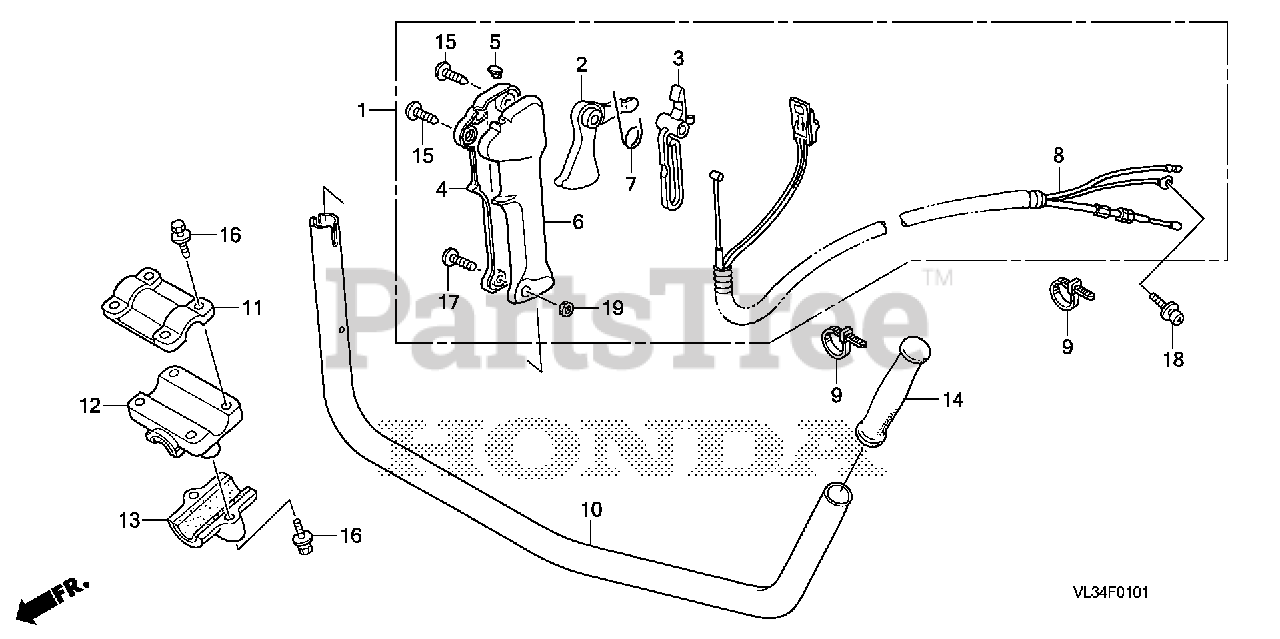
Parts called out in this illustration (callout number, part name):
1	LEVER ASSY., THROTTLE (U)
2	LEVER, THROTTLE (YELLOW)
3	LEVER, THROTTLE LOCK (YELLOW)
4	GRIP, R. THROTTLE LEVER
5	CAP, THROTTLE LEVER
6	GRIP, L. THROTTLE LEVER
7	SPRING, THROTTLE LEVER
8	WIRE HARNESS ASSY.
9	TIE, CABLE (157.5MM)
10	PIPE, HANDLE
11	HOLDER A, HANDLE
12	HOLDER B, HANDLE
13	HOLDER C, HANDLE
14	GRIP, HANDLE
15	SCREW, TAPPING (4X20)
16	BOLT-WASHER (5X28)
17	SCREW, PAN (5X30) (NOT AVAILABLE)
18	SCREW-WASHER (5X12)
19	NUT, HEX. (5MM)
